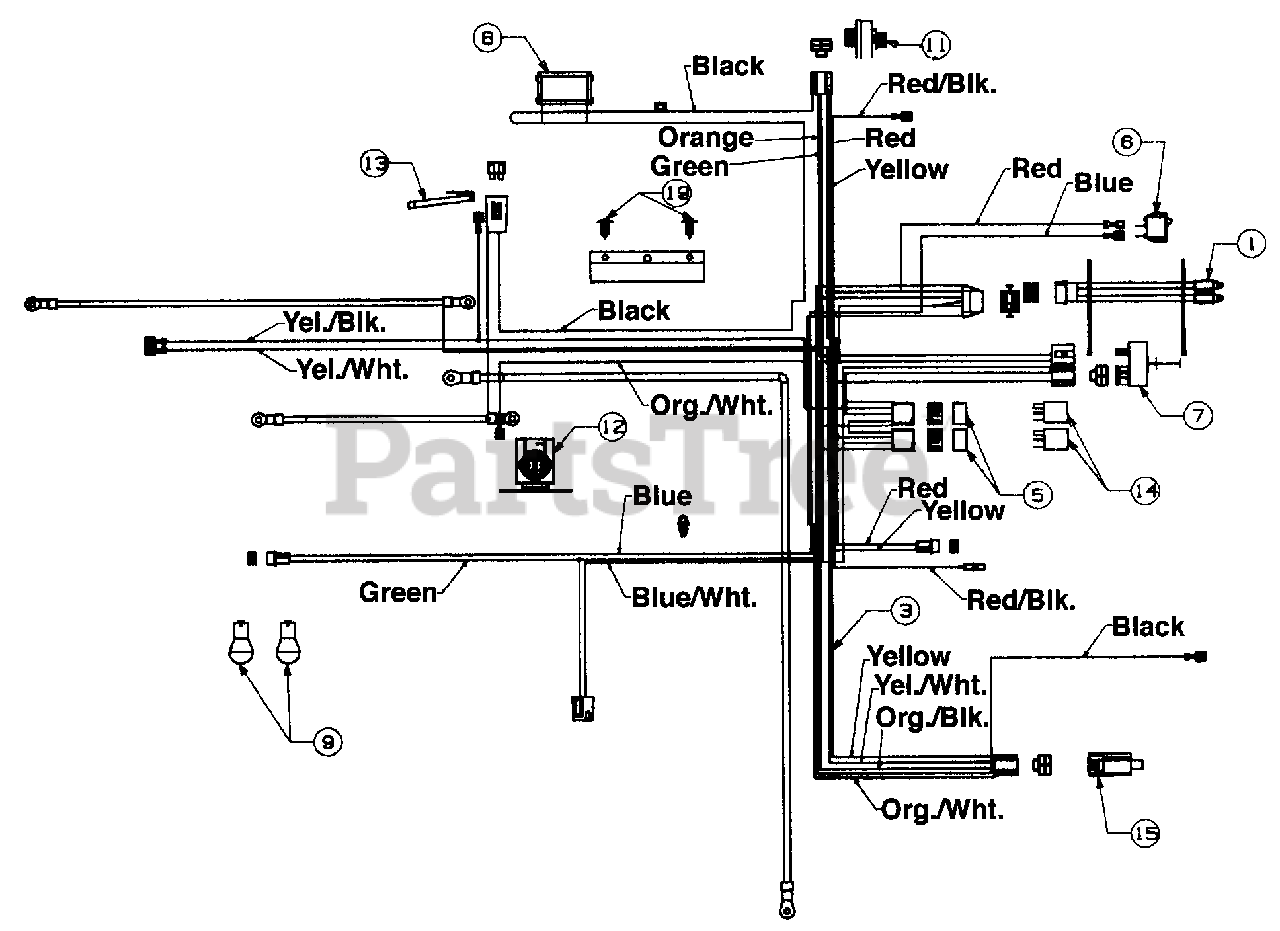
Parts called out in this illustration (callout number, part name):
1	Wire Harness (Monitor)
3	Wire Harness
5	Gasket - Relay
6	Light Switch
7	PTO Switch
8	Ammeter
9	Bulb (Headlight)
11	Ignition Switch
12	Solenoid
13	Safety Switch (Reverse)
14	Relay
15	Safety Switch
